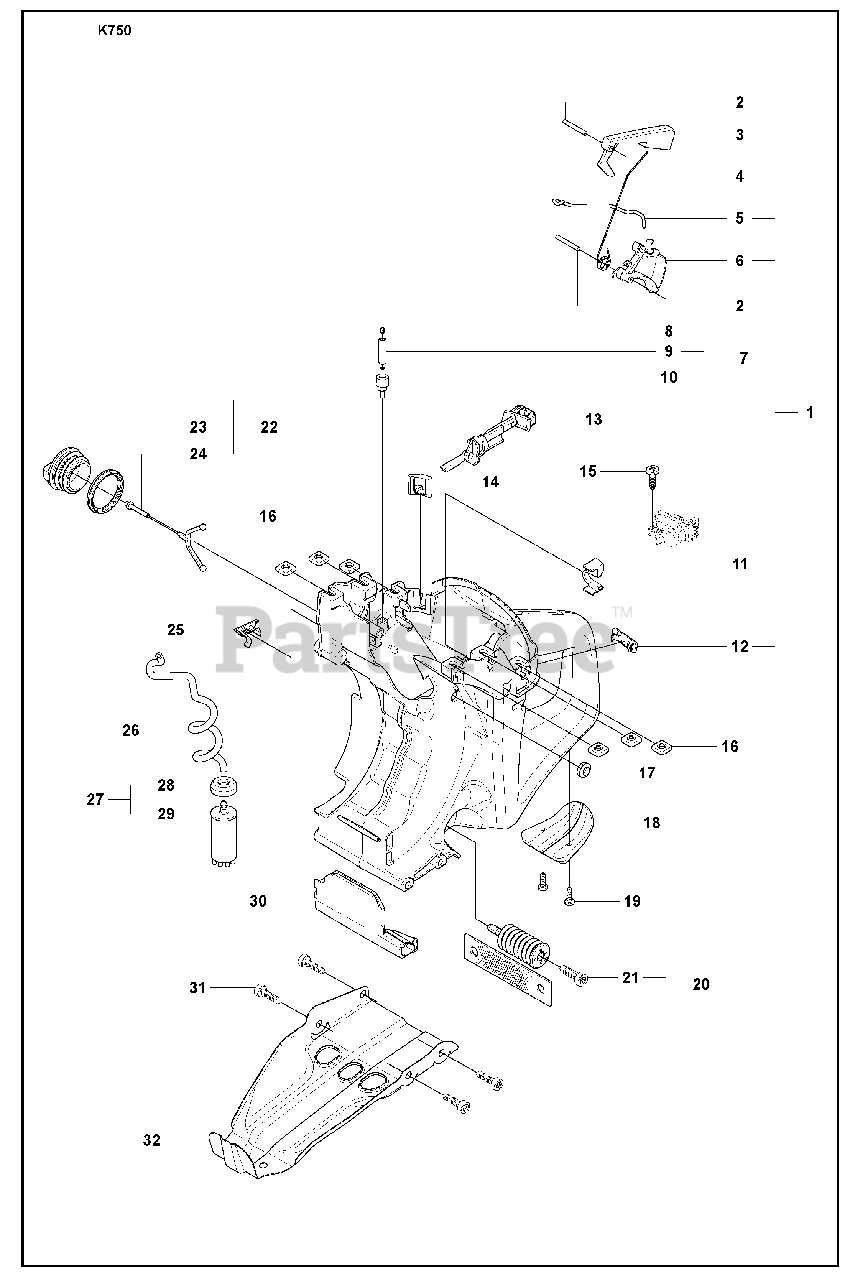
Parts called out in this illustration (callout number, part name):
1	FUEL TANK
2	PARALLEL PIN
3	THROTTLE LOCKOUT
4	SPRING
5	THROTTLE ROD
6	THROTTLE TRIGGER
7	TANK VENT ASSY
8	SINTER PLUG
13	CHOKE CONTROL
17	CABLE GROMMET
18	GROUND SUPPORT
20	VIBRATION ABSORBER
22	TANK CAP ASSY
24	TANK CAP HOLDER
25	CAP
26	FUEL HOSE
27	FUEL FILTER
28	HOSE CLAMP
29	FUEL FILTER
30	HEAT SHIELD
32	BASE PLATE
